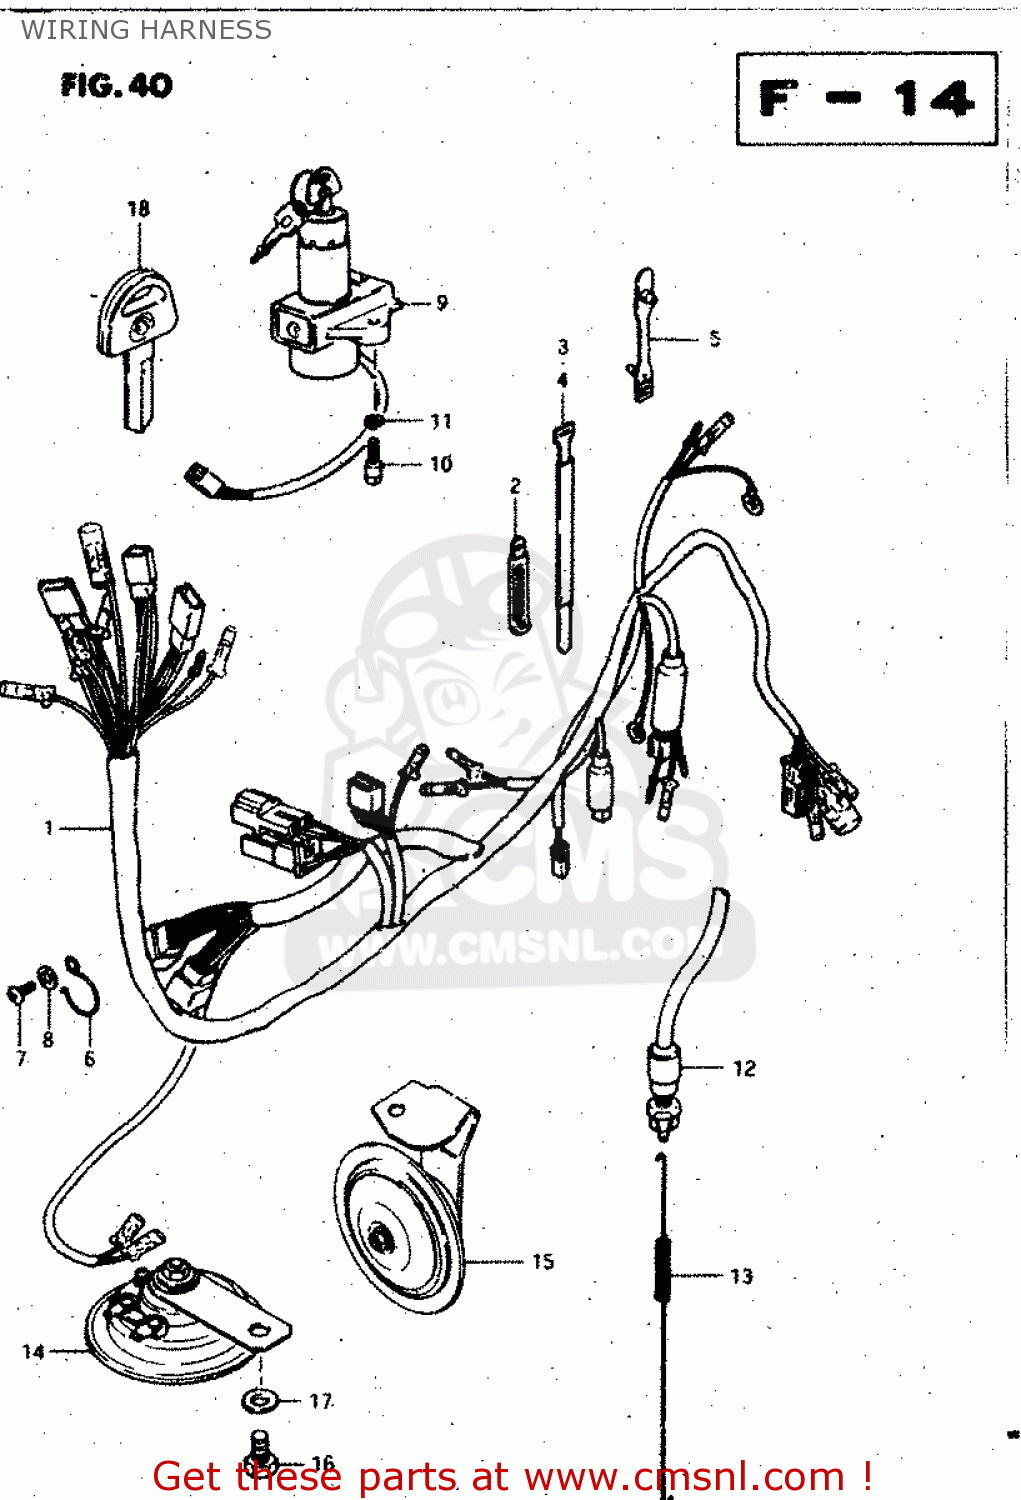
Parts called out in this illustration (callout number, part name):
1	WIRING HARNESS
2	CLAMP
3	CLAMP(L:80)
4	CLAMP
5	CLAMP,L:88
6	GUIDE,WIRING HARNESS
7	SCREW 6X12
8	WASHER
9	LOCK ASSEMBLY,STEERING
10	BOLT
11	LOCK WASHER
12	SWITCH ASSEMBLY,STOP LAMP
13	SPRING
14	HORN ASSEMBLY,LOW PITCH
15	HORN ASSEMBLY
16	BOLT 8X12
17	WASHER
18	KEY,BLANK
